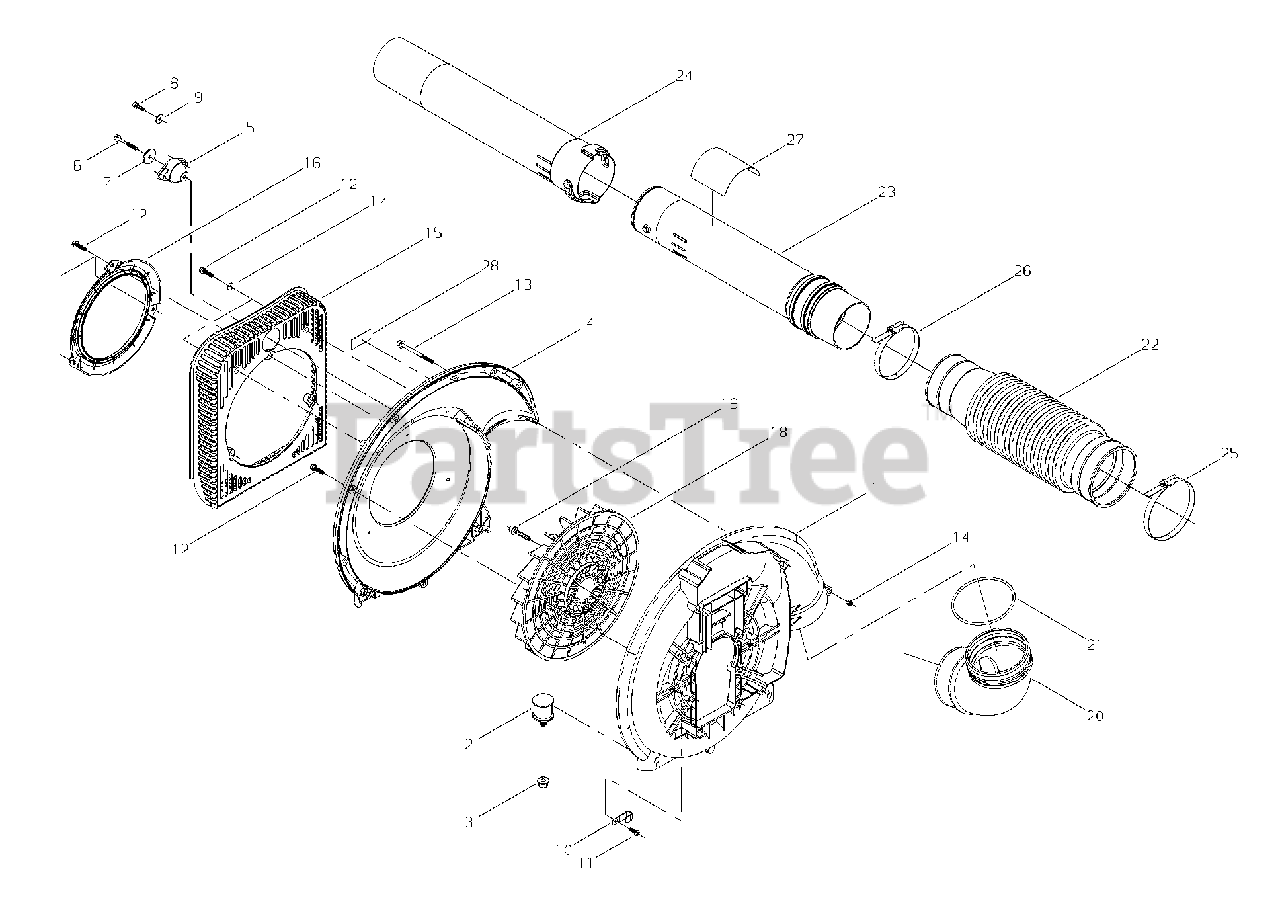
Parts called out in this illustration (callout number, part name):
1	COVER, FAN - OUTER
2	CUSHION
3	NUT - 6 -- FLANGE
4	COVER, FAN - INNER
5	CUSHION
6	BOLT - 5 -- TAPPING
7	COLLAR - 25X5.5X2
8	SCREW - 5X16
9	COLLAR
10	CLAMP
11	SCREW - 5X14 -- TAPPING
12	BOLT - 5X20
13	SCREW - 5X70
14	NUT - 5
15	COVER, INTAKE
16	FUNNEL
17	WASHER - 5
18	FAN
19	SCREW - 6X35
20	BEND PIPE
21	O-RING
22	FLEXIBLE TUBE
23	TUBE, BLOWER - SWIVEL
24	NOZZLE - 74mm
25	CLAMP
26	CLAMP
27	LABEL - MODEL
28	LABEL - CAUTION
